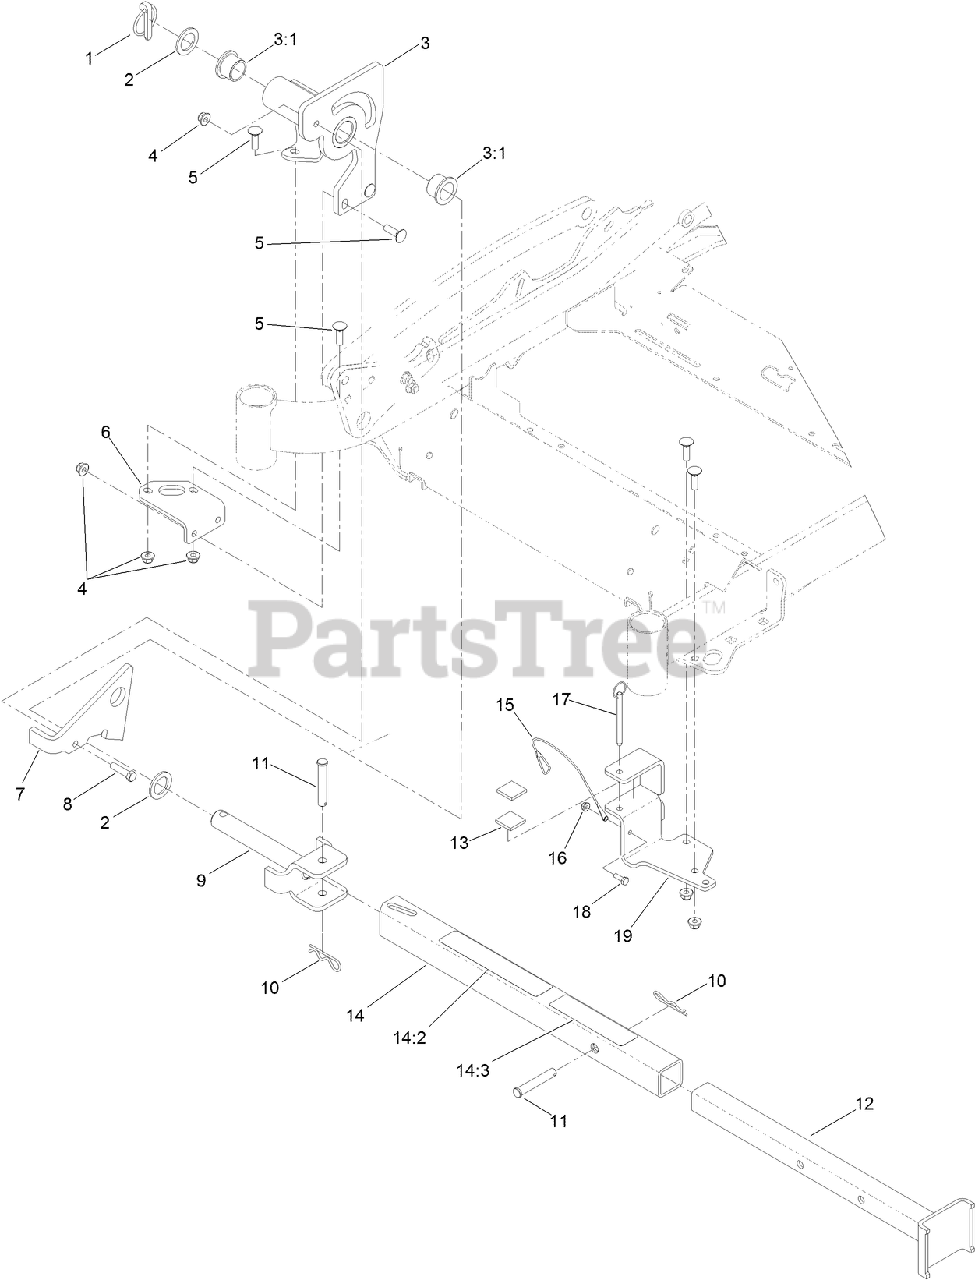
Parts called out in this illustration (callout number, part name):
1	PIN-LYNCH
2	WASHER-THRUST
3	Z STAND PIVOT ASM
3:1	BUSHING
4	NUT-HF, NI
5	BOLT-CARR
6	BRACKET-MOUNT, PIVOT
7	BRACKET-LATCH
8	SCREW-HH
9	PIN-PIVOT
10	PIN-HAIR
11	PIN-CLEVIS
12	TUBE-INNER
13	CUSHION-RUBBER
14	OUTER TUBE ASM
14:2	DECAL-Z STAND
14:3	DECAL-WARNING
15	LANYARD-NYLON
16	NUT-HF
17	PIN-HITCH, COTTERLESS
18	SCREW-HH
19	CRADLE-Z STAND
